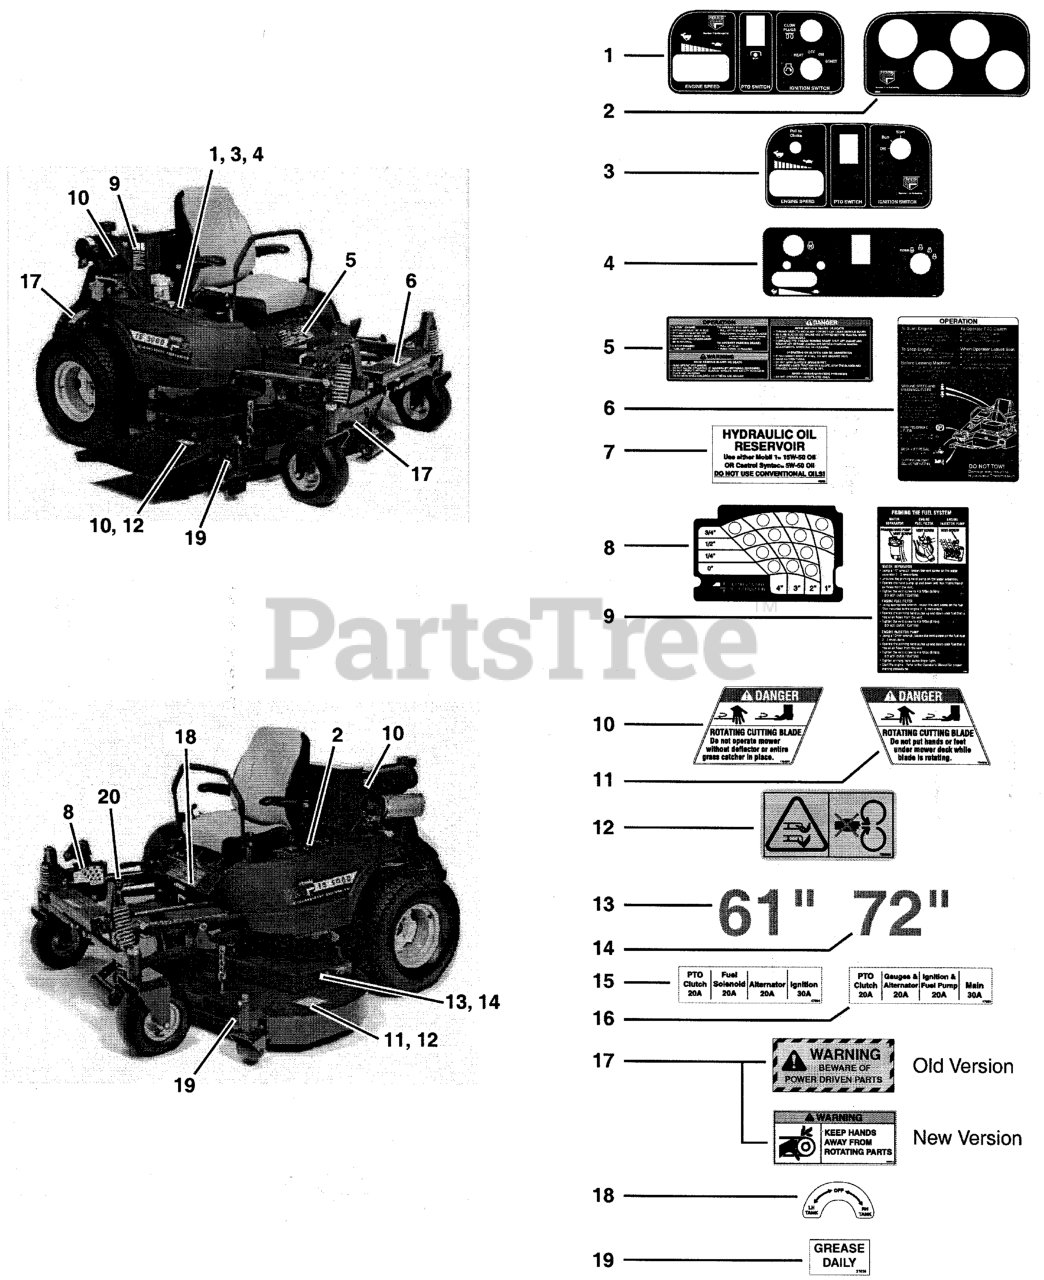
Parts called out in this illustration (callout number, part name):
1	DECAL, Instrument Panel
2	DECAL, Gauge Panel
3	DECAL, Control Panel-RH
4	DECAL, Control Panel
5	DECAL, Instruction/Safety
6	DECAL, Operation
7	DECAL, Oil Reservoir
8	DECAL, Deck Height
9	DECAL, Priming Instructions
10	DECAL, Danger (Chute In Place)
11	DECAL, Danger (Hand Under Deck)
12	DECAL, Warning, Mower
13	DECAL, 61"
14	DECAL, 72"
15	DECAL, Fuse Location
16	DECAL, Fuse Location
17	DECAL, Warning
18	DECAL, Fuel Valve
19	DECAL, Grease Daily
20	Model/Serial Number Tag
